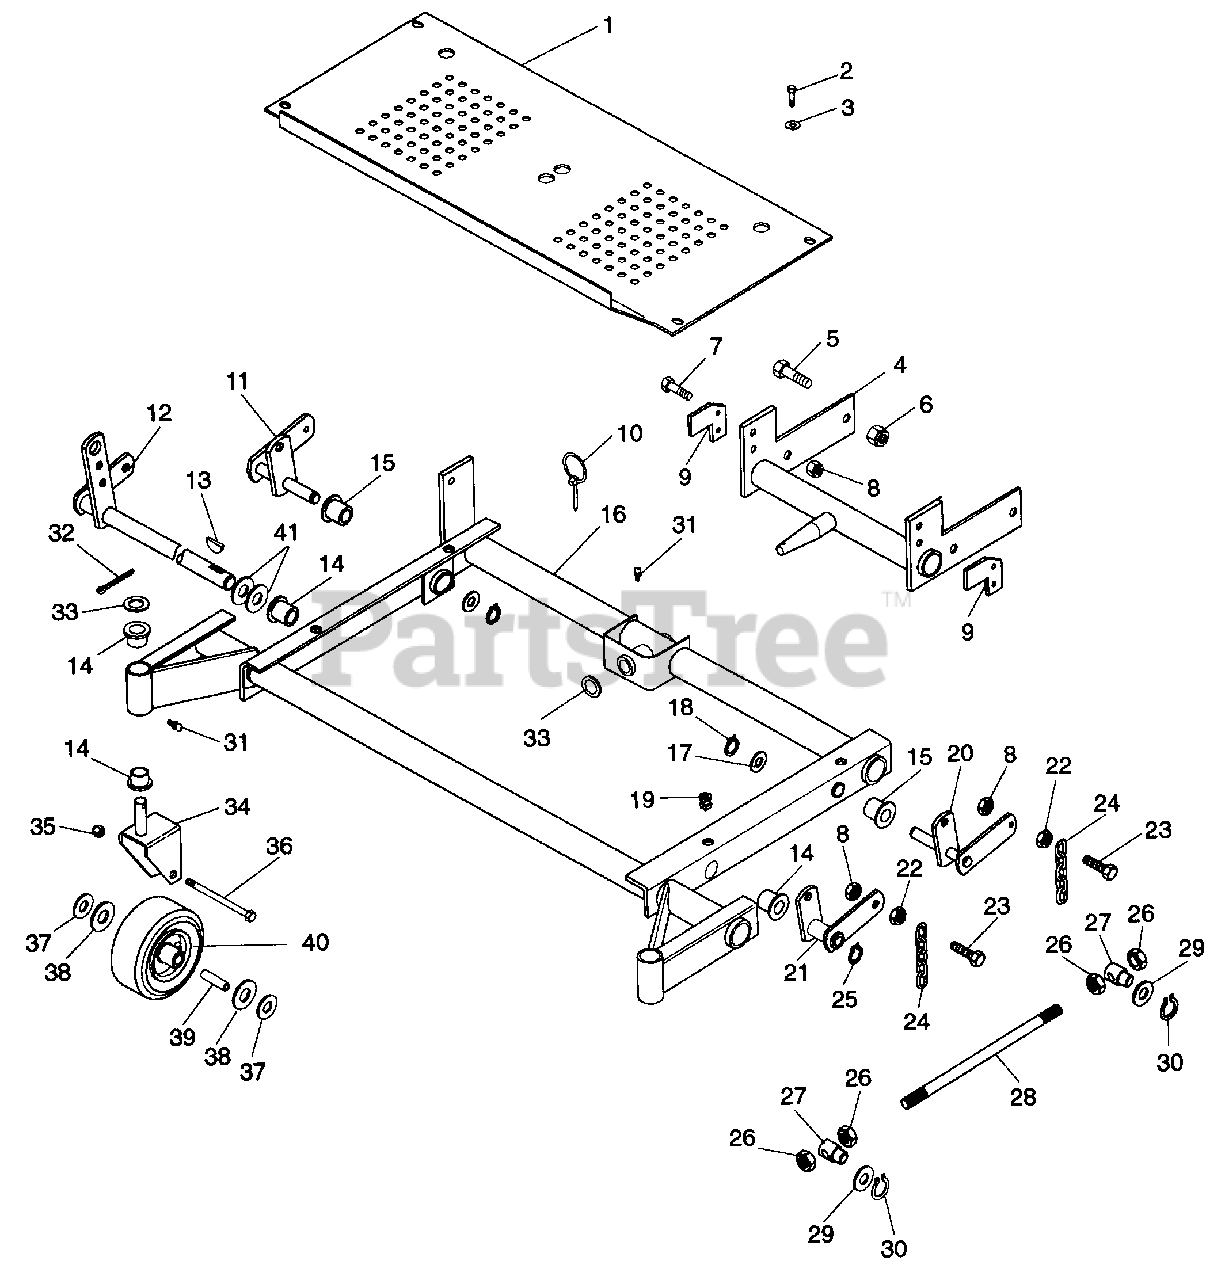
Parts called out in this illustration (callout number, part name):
1	FOOTBOARD PM200
2	SCR-MCH .25-20 PAN HP
3	WSHR-FL-STL .281 X .625 X .065
4	WLDMT, MWR FRAME MTG
5	BLT-HEX .625-11 X 1.50
6	NUT-LK-NYL .625-11 PL
7	BLT-HEX .38-16 X 1.125
8	NUT-LK-NYL .375-16 PL
9	PLATE, PIVOT STOP
10	PIN-KLIK .25 X 1.75
11	WLDMT. LIFT ARM SHAFT R.H.
12	WLDMT, MWR LIFT SHAFT(FRT)
13	KEY-WDRF .25 X 1.0 HRD # 15
14	BSHG-FLG 1.020 X 1.75 X .75 NY
15	BSHG-FLG .762 X 1.0 X .580 X 1.48
16	WLDMT, FRONT FRAME PM200
17	BRG-N-THRUST .752 X 1.24 X .031
18	RG-RTNG-EXT .689 X .077
19	CLIP, U-TYPE EATON #C17453-1420
20	WLDMT, LIFT ARM SHAFT(L.H.)
21	WLDMT LIFT ARM(FRT)
22	NUT-HEX .375-16
23	BLT-HEX .38-16 X 1.50 PL GR 5
24	CHAIN, LINK
25	RG-RTNG-EXT 1.00 X .078
26	NUT, 50-13 PL
27	PIVOT, MWR LIFT
28	TIE ROD, LIFT LEVER
29	WSHR-FL-STL .630 X 1.005 X .062
30	RG-RTNG-EXT .625 X .050
31	FTG, LUBE .25-28 SELF THREAD
32	PIN-COTR .12 X 1.25 PL
33	BRG-R-THRST 1.002 X 1.552 X .030
34	WLDMT, CASTER FORK
35	NUT-LK-NYL .50-13 PL
36	BLT-HEX .500-13 X 8.00
37	WSHR-FL-STL .531 X 1.25 X .100
38	WSHR-FL-STL .813 X 1.370 X 1.00
39	AXLE, CASTER
40	T/WHL ASSY 13 X 5-6 TURF TRAC RS
41	WSHR-FL-STL .063 X 2.000 X .134
NS	TIRE 13 X 5-6 TURF TRAC RS
